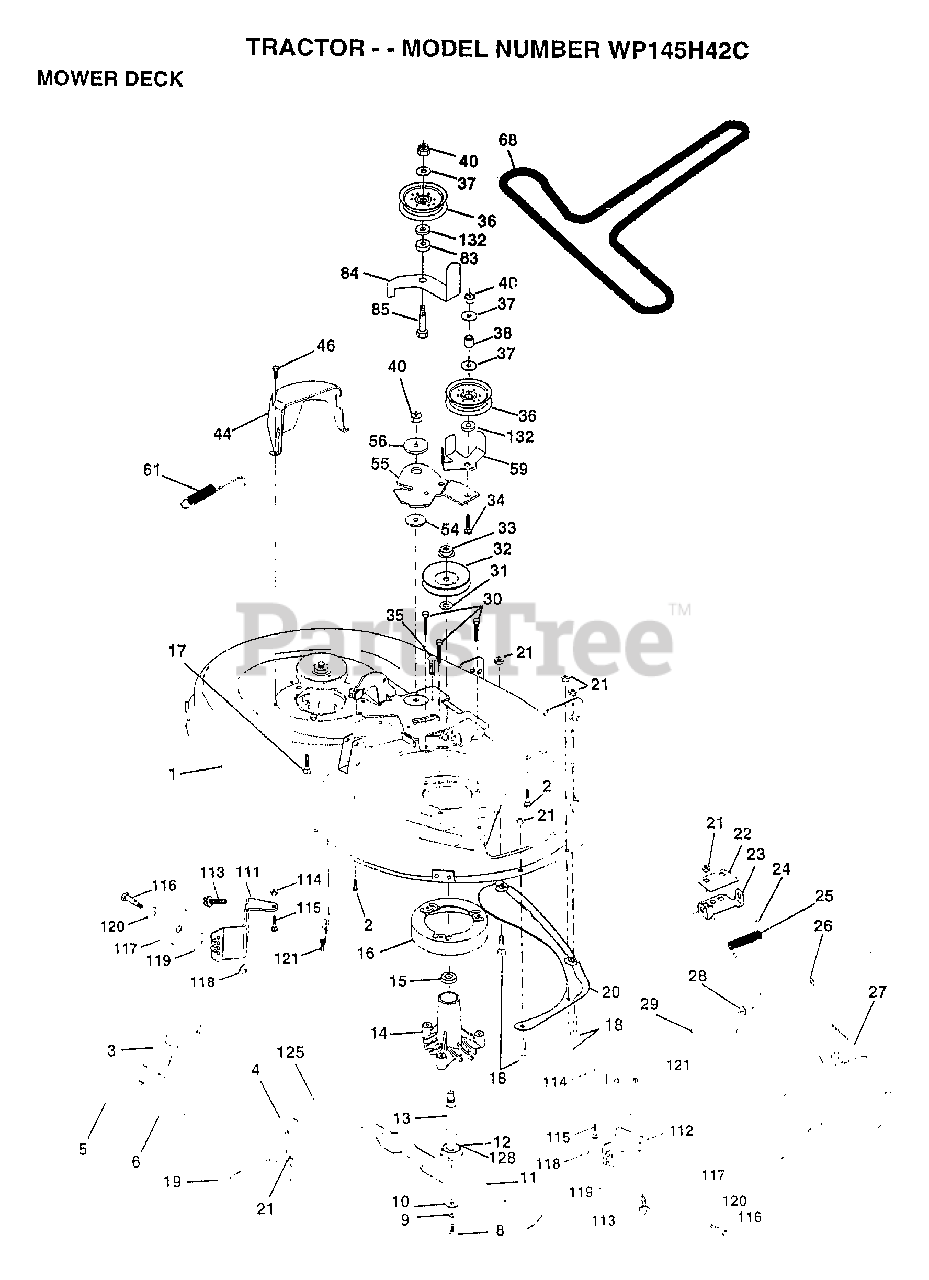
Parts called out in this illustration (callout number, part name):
1	DECK.WELD.42.
2	BOLT
3	BRKT ASM SWAY BAR
4	BRKT DECK SW BAR
8	BLADE BOLT
10	WASHER.HARD.BLADE
11	"BLADE.42"" HIPERF"
12	BEARING.BALL
14	HSG ASM MANDREL
15	BEARING
16	STRIPPER RND MWR
17	BOLT CARRIAGE
18	BOLT
19	BOLT SHD 5/16-18
22	STIFFENER BRKT
23	DEFLECTOR BRKT
24	CAP-SLEEVE LT
25	SPRING TORSION
26	NUT PUSH M
27	DEFLECTOR.SHIELD
28	WASHER
29	HINGE ROD
31	WASHER
32	PULLEY.MANDREL.42
34	BOLT
35	XMAS TREE FASTNER
36	FLAT IDLER PULLEY
37	WASHER
44	GUARD MAND LH BLK
46	SCREW.1/4-20X5/8
54	HARDENED WASHER
55	ARM-IDLER
56	SPACER RETAINER
59	GUARD IDLER TUV
61	SPRING.EXTENSION
68	BELT.V.T-PATH
83	WASHER
84	"KEEPER-BELT,FIXED"
85	BOLT RDHD 3/8-16
111	BRACKET.GWHL.LH.
112	BRACKET.GWHL.RH.
113	SCREW
116	BOLT M
117	WHEEL.GAGE.BLK.PL
118	LOCKNUT
119	WASHER
120	WASHER
121	BRACKET.EXTRD.GWL
125	COTTER PIN
128	WASHER.FELT.
132	WASHER GT
